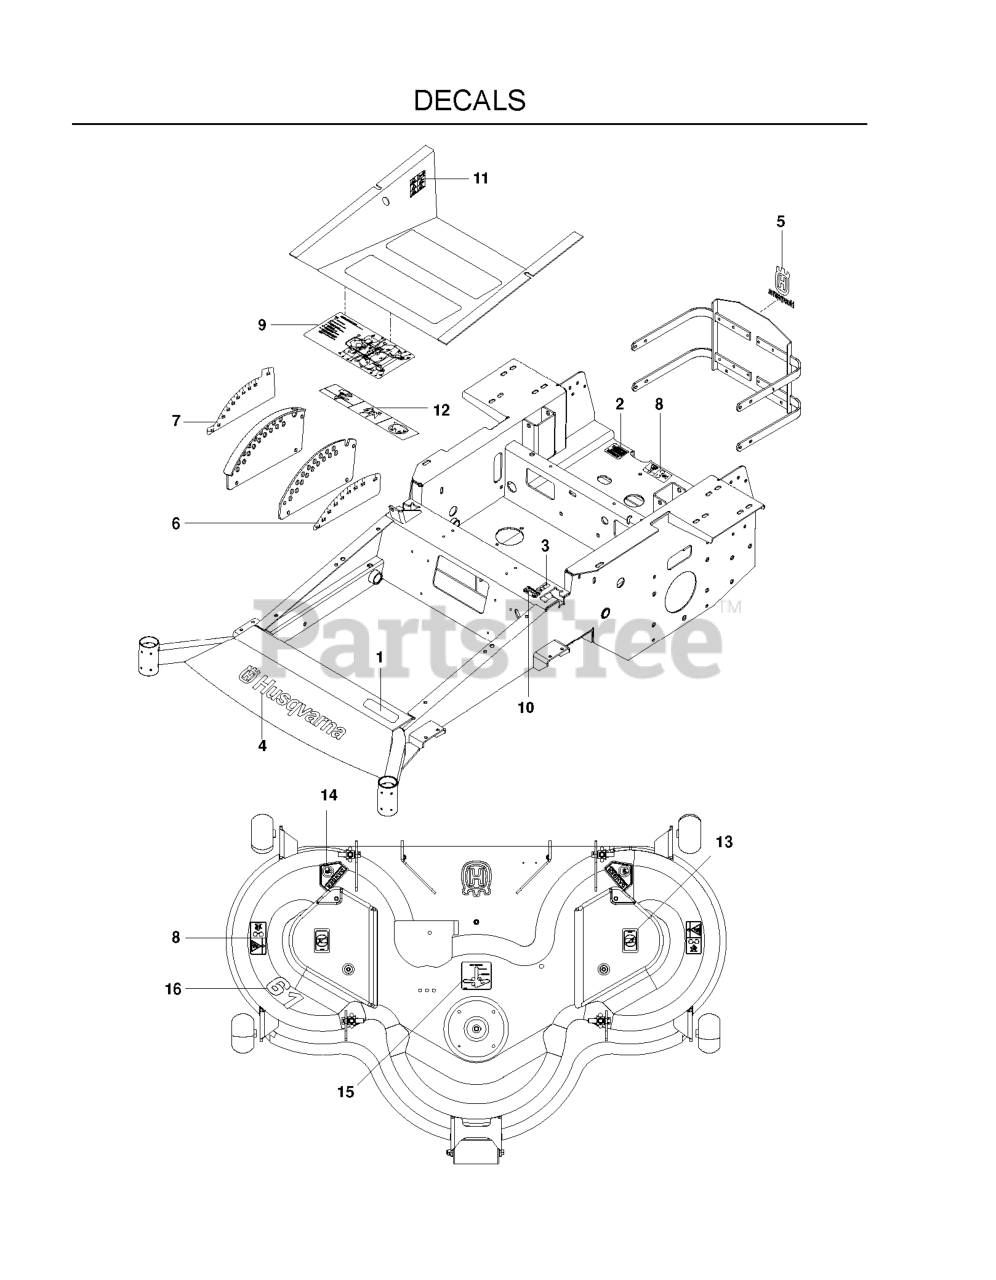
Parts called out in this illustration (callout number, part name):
1	DECAL, LZ5227
2	DECAL, PROP. 65
3	DECAL, MOTION CONTROL
4	DECAL, HUSQ 15" BLUE
5	DECAL, CROWN H 5-1/4 SILVER
6	DECAL, HEIGHT
7	DECAL, HEIGHT
8	DECAL, BELT DRIVE
9	DECAL, SERVICE
10	DECAL, F.S.T.
11	DECAL, WARNING
12	EURO DECAL-BATTERY WARNIN6
13	DECAL, NO STEP
14	DECAL, CPSC
15	DECAL, BELT ROUTING
16	LABEL
